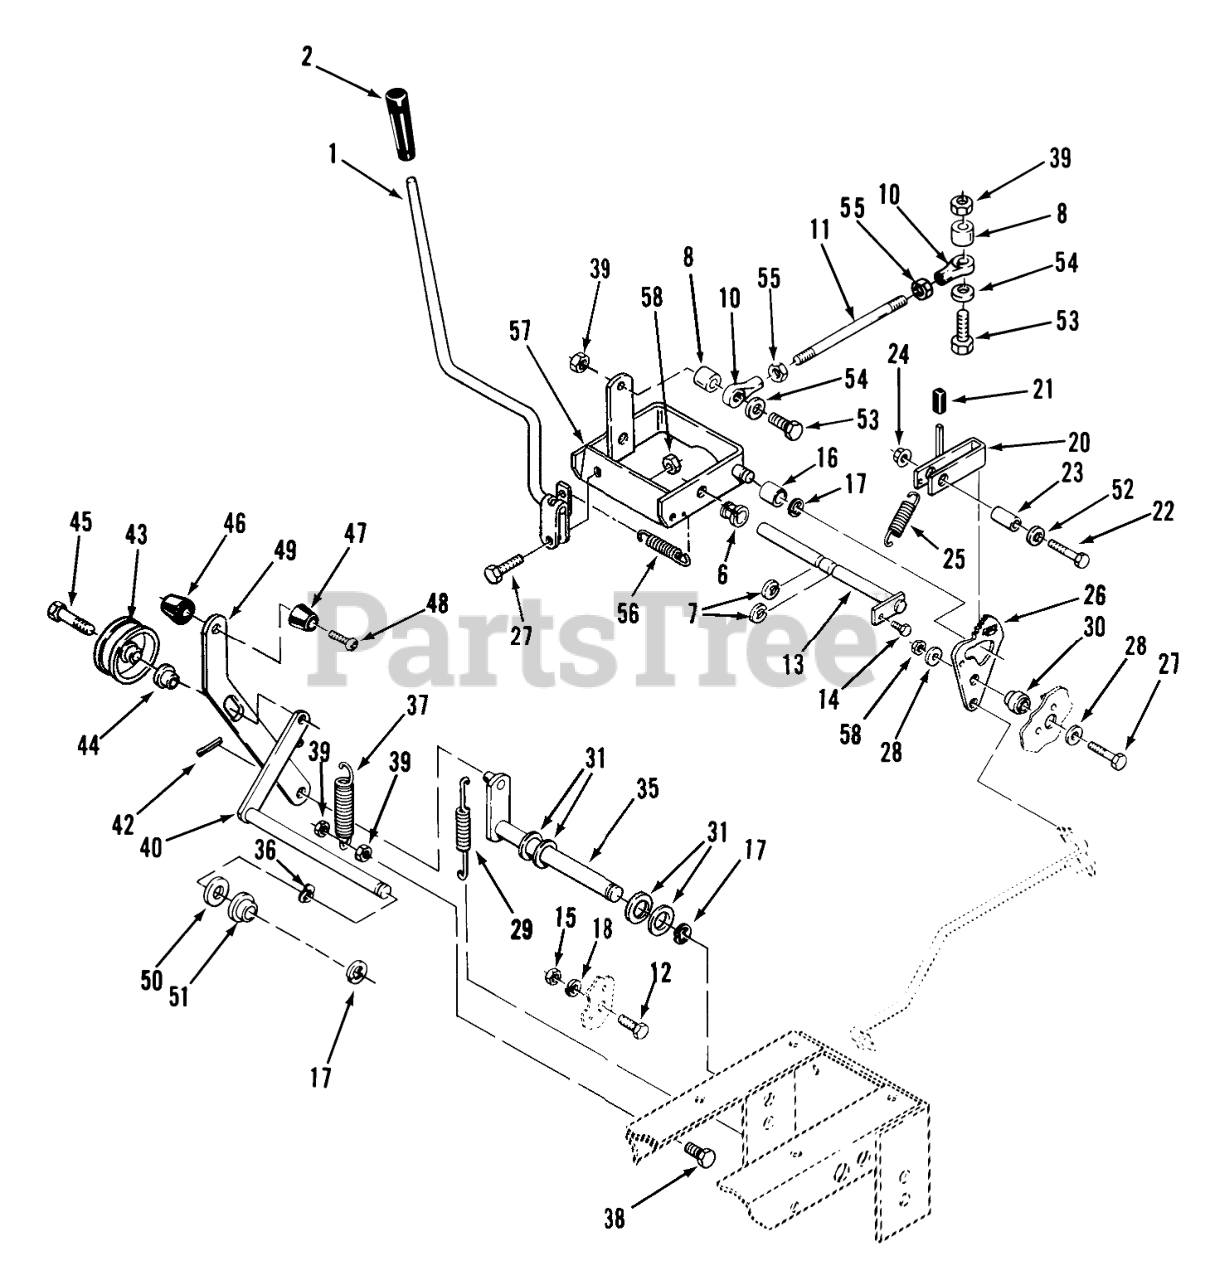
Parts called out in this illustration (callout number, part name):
1	Motion Control Lever (VIN-S 31-18OE01, 31-20OE01, C1-20OE01)
1	ASS'Y-ARM CONTROL B
2	KNOB
6	NYLINER BUSHING
7	E Ring
8	Spacer
10	ASSY ROD END
11	ROD CONTROL
11	ROD-CONTROL
12	Bolt
13	ASSY-ROD CAM PIVOT
14	SCREW
15	Nut
16	BEARING-CAM RETURN
17	E Ring
18	LOCKWASHER
20	PAWL HDL ASSY B
21	VALVE LEVER GRIP
22	Bolt
23	SPACER
24	LOCKNUT-FLANGE
25	Spring
26	Cam Plate
27	BOLT
28	Washer
29	SPRING-EXTENSION
30	Spacer
31	Washer
35	ASSY-BRAKE LEVER
36	WASHER-WAVE
37	SPRING-EXTENSION
38	Bolt
39	Nut
40	ASSY-ARM/ROD WA
40	Pivot Rod
42	Cotter Pin
43	PULLEY-IDLER
44	SPACER-BRAKE LINK
45	BOLT-SPECIAL HEX
46	KNOB
47	KNOB
48	BOLT-4
49	Handle
50	Washer
51	BUSHING-FLANGED
52	Washer
53	Bolt
53	Bolt 1/4-20 X 1 1/2
55	Jam Nut 1/4-28
56	SPRING
57	Cam Comtrol
58	NUT
